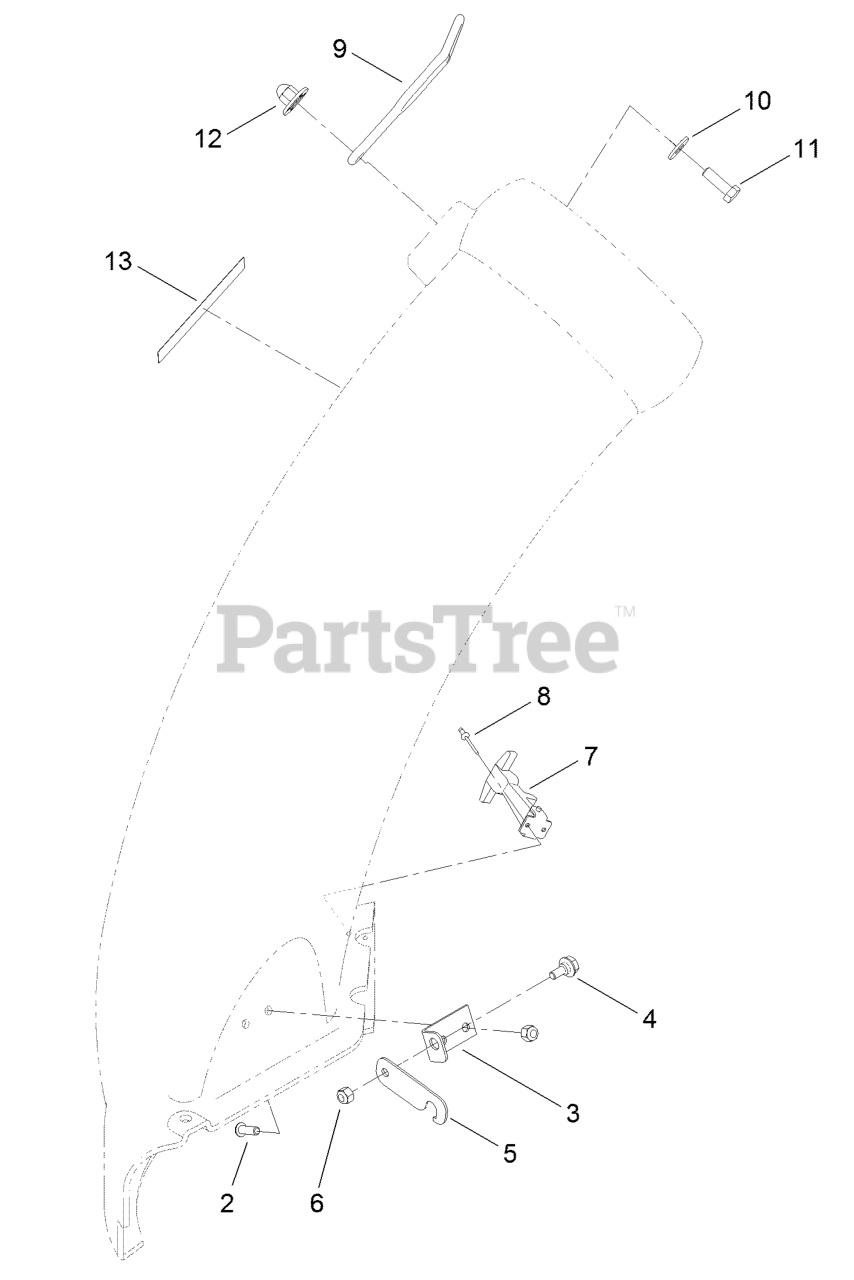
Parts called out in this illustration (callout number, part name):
2	SCREW-HSBH
3	PLATE-PIVOT
4	SCREW-SHOULDER,HWH
6	NUT-LOCK, NI
7	HANDLE ASM
8	RIVET-POP
9	RETAINER-DUCT
10	WASHER-FLAT
11	SCREW-HH
12	NUT-IMPELLER
13	DECAL-DANGER
